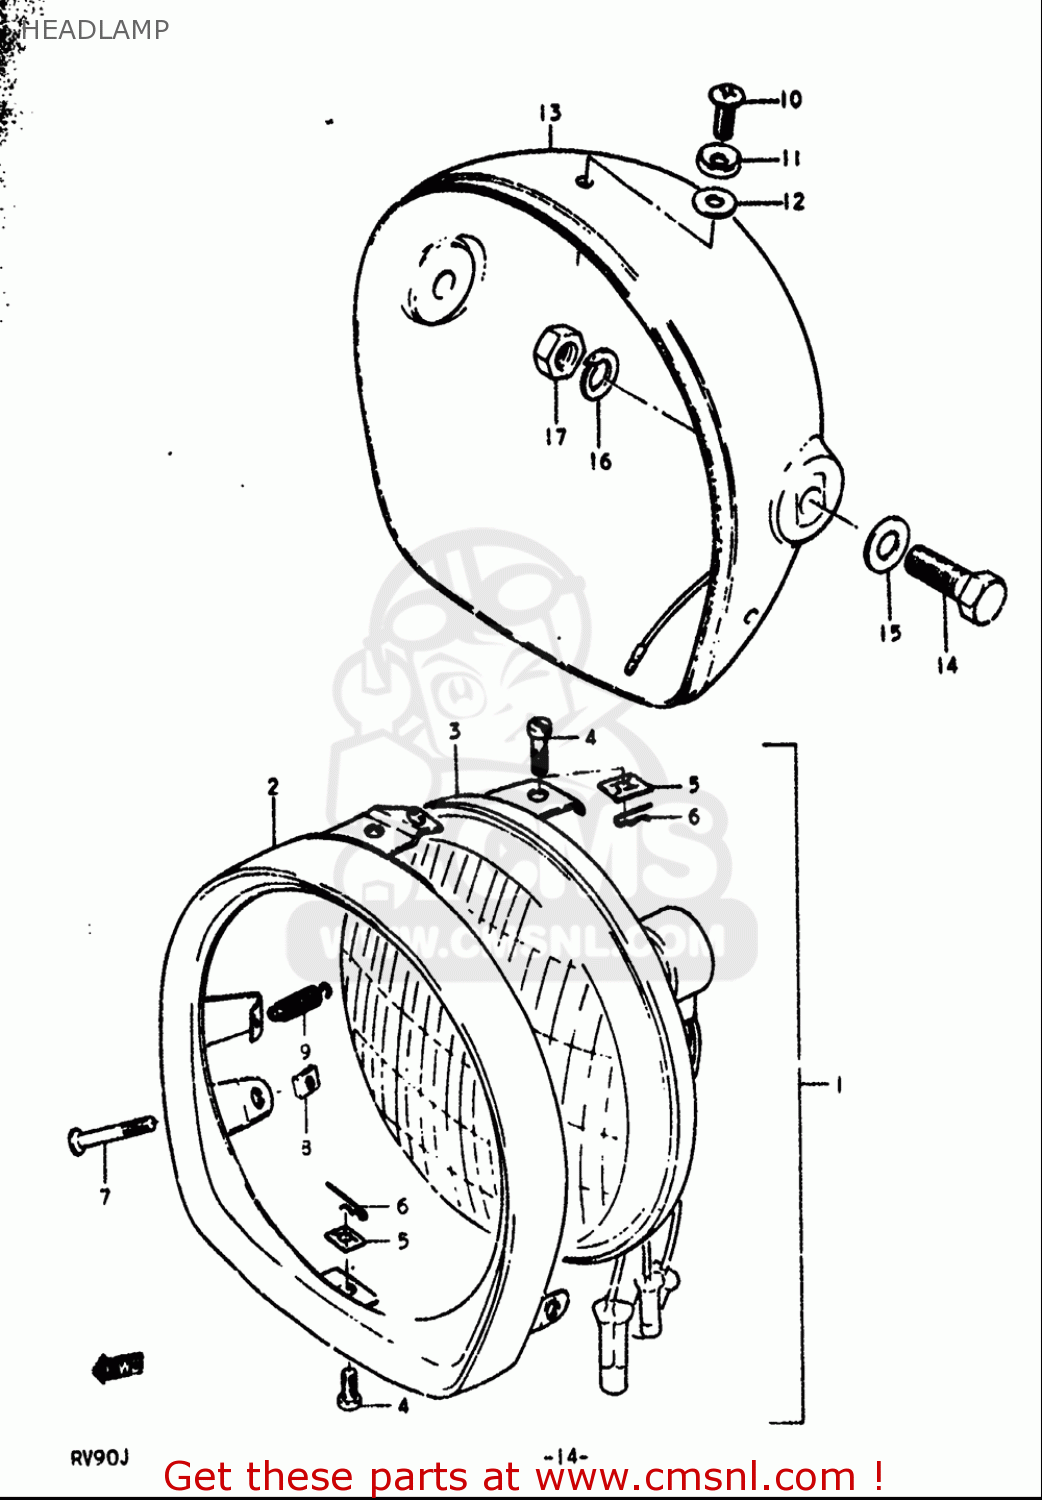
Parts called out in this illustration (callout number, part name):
5	NUT
7	SCREW,HEADLAMP ADJUST
8	NUT,HEADLAMP ADJUSTER
9	SPRING,HEADLAMP ADJUST
10	SCREW
11	WASHER
12	WASHER(4X12.5X0.3)
14	BOLT
15	WASHER
16	WASHER,LOCK
17	NUT
